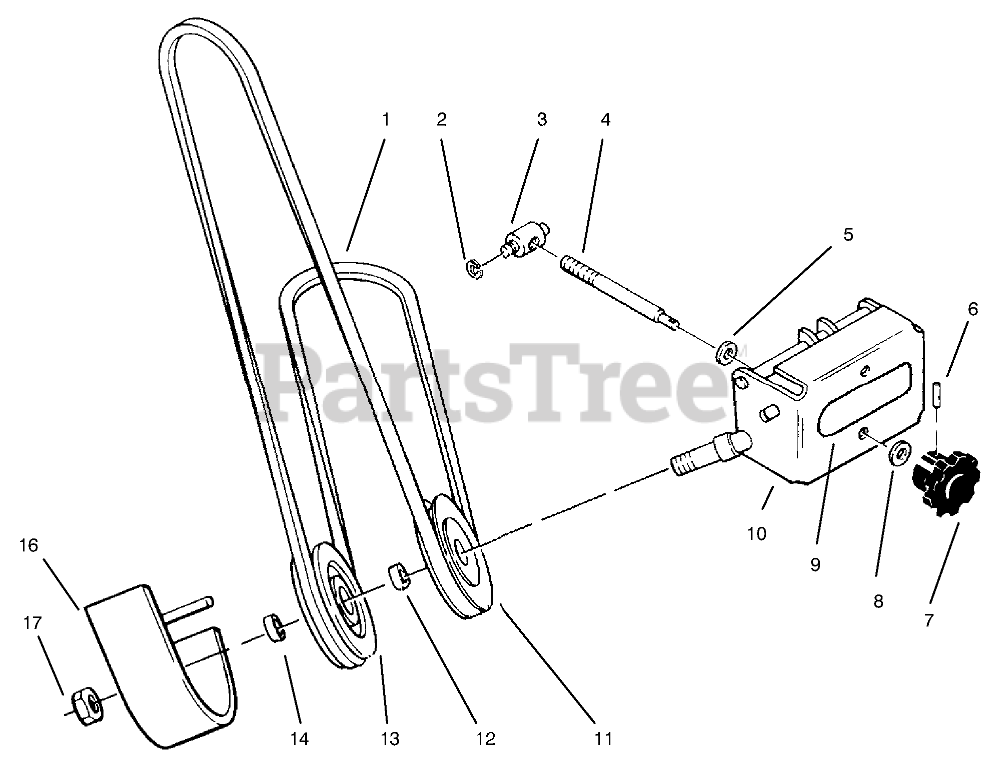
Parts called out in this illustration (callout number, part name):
1	V-BELT
2	RING-RETAINING
3	TRUNNION-DOUBLE
4	ROD ADJ
5	WASHER-FLAT
6	PIN-ROLL
7	KNOB-ADJUSTMENT
8	WASHER-SPRING
9	DECAL-ATTACH A-MATIC
10	Front Support
11	PULLEY-IDLER
12	SPACER
13	PULLEY-FLAT IDLER
14	SPACER-OUTER
16	Belt Cover
17	Nut
